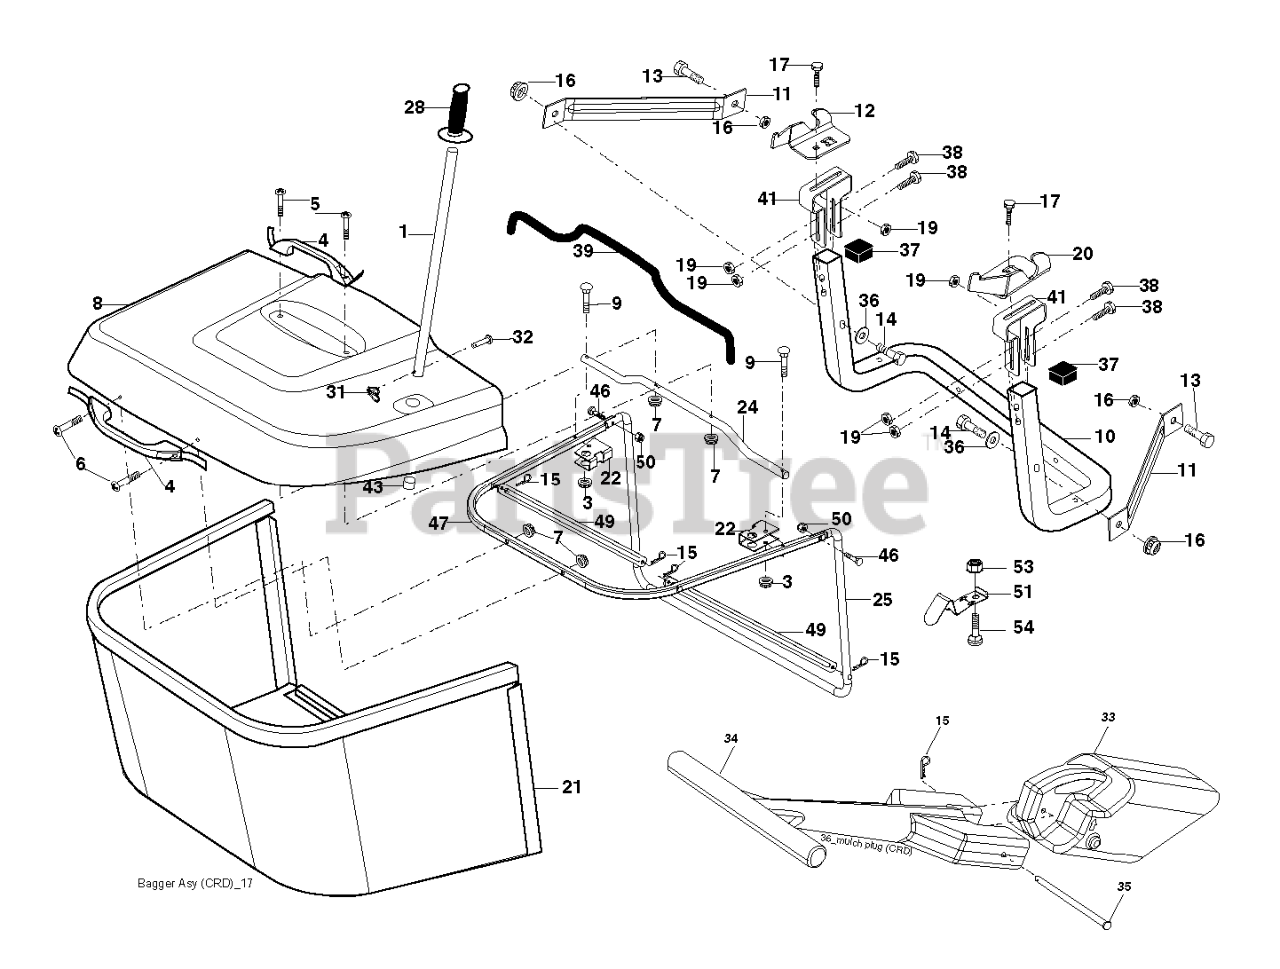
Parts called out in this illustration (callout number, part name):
1	TUBE HANDLE
3	NUT T
4	HANDLE.BAGGER.W/LVRS.BLK.CRD
5	SCREW.PAN.HEAD
6	REPL BY 532 75 00-29
8	COVER.PNT.BGR.CRD.WSLOTS.MS668
9	Bolt Carriage 1/4-20 x 2.25d x Gr.5
10	TUBE
11	BRACKET.SUPPORT.UPPER.BAG.CRD
12	BRKT PIVOT
14	BOLT-HEX EAK
15	RETAINER-SPRNG RB
16	NUT LOCK FLG 3/8-16 UNC
17	RP BOLT 5/16-18 X3/4 ZN/YEL GR
19	NUT LOCK HEX FLANGE 5/16-18
20	BRKT.PIVOT.RH.CRD
21	BAGGER.ASM.CRD.2007
22	BRKT.SIDE.BAG.CRD
24	TUBE.PIVOT.BAG.CRD.BLACK
25	PIPE
28	GRIP.HANDLE.BLACK
31	RETAINER CLIP
32	RIVET,DRILLED
33	MULCH PLUG, CTH150
34	HANDLE.MULCHER.92.CRD (2 2)
36	WASHER
37	Plug Support Bagger CRD
38	BOLT.5/16-18X2.5
39	SEAL.BAGGER.CRD
41	BRKT.VERT.ADJ.BAGGER.CRD
43	PLUG, TUBING END
46	BOLT.CARRIAGE.5/16-18
47	PIPE
49	ROD
50	NUT.71038.31-18.HEX.NYLOCK
51	LATCH
53	NUT
54	BOLT
